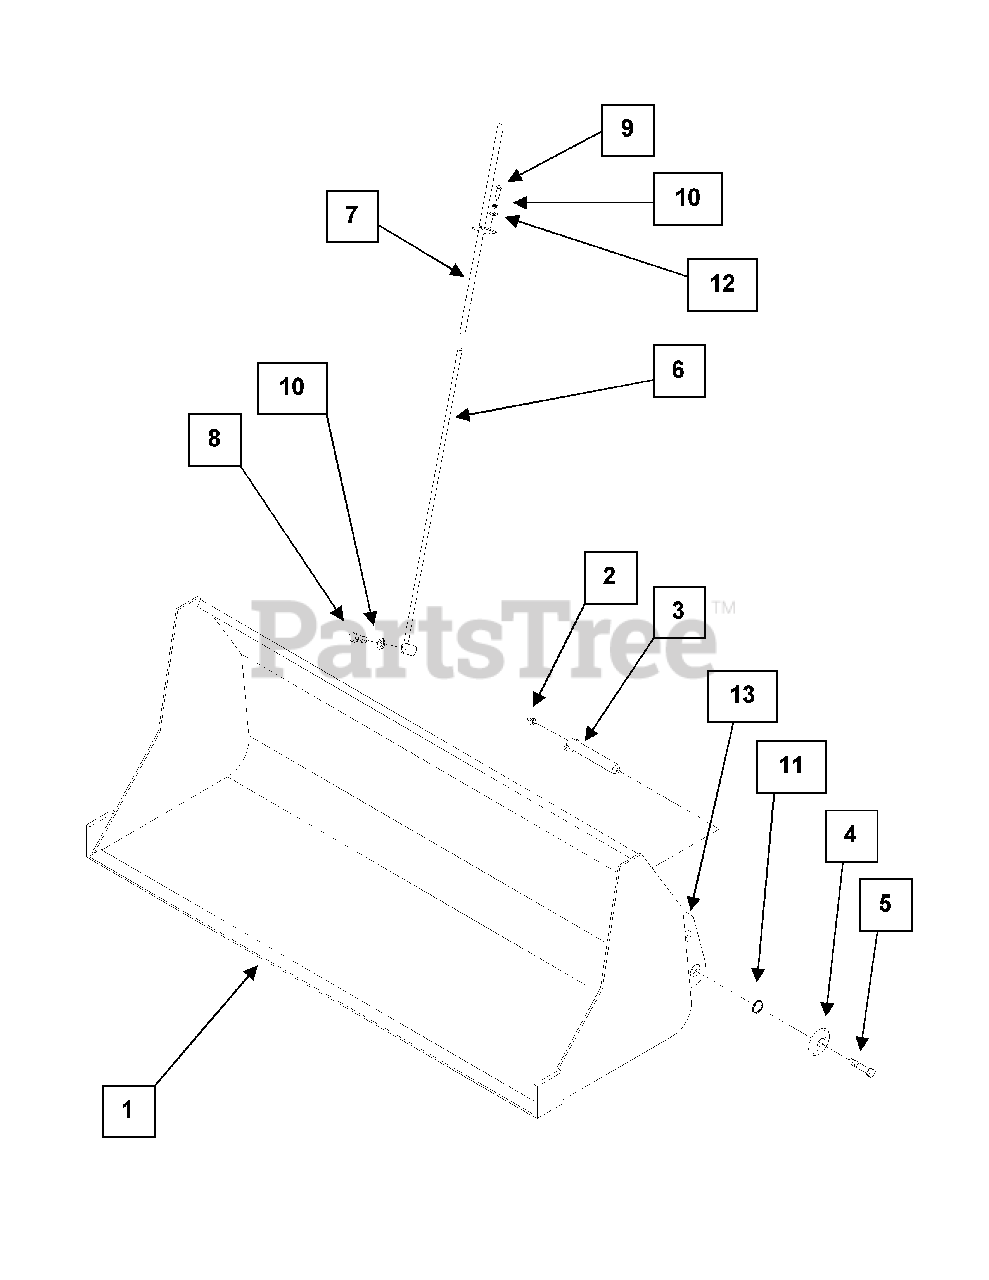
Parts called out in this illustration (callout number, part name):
1	Bucket Assembly, 66"
2	Grease Fitting
3	Pivot Pin, 1" x 103mm
5	Hex Head Cap Screw, 5/16" x 3/4"
6	BLI Rod Assembly
7	BLI Tube Assembly
8	Hex Head Cap Screw, 5/16" x 1-1/2
9	Hex Head Cap Screw, 5/16" x 1/2"
10	Lock Washer, 5/16"
12	Flatwasher, 5/16"
13	Tool Carrier
